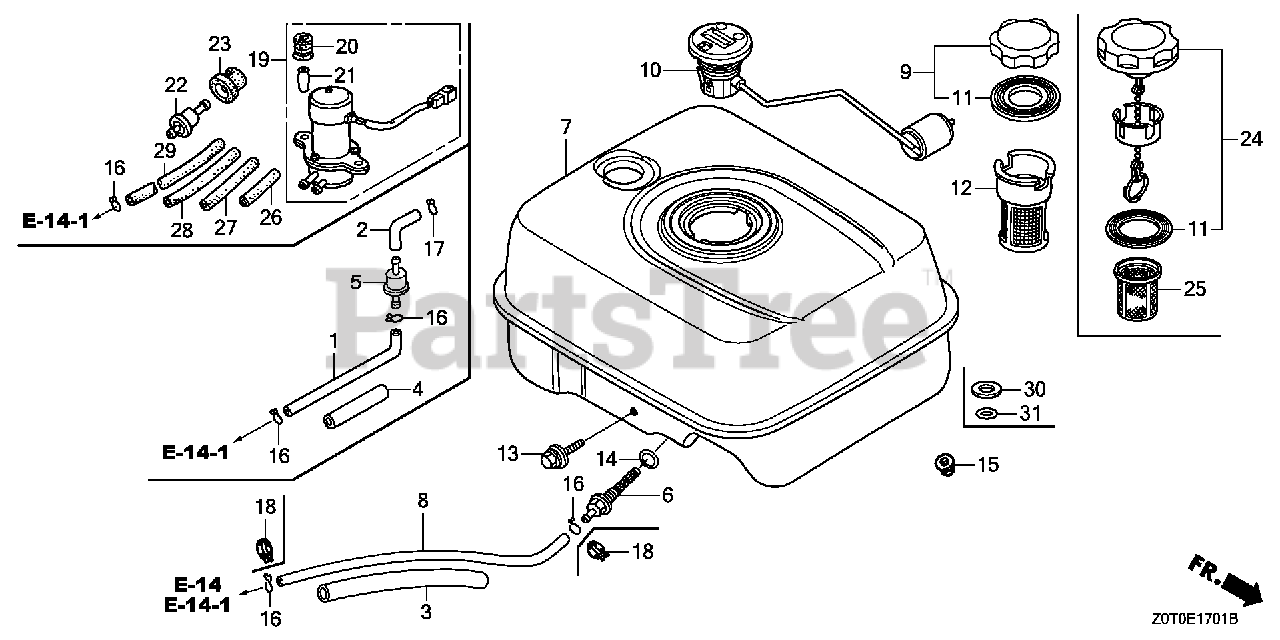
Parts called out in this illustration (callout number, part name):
3	RUBBER, SUPPORTER (107MM)
6	JOINT, FUEL TANK
7	TANK, FUEL *NH31* (MCKINLEY WHITE)
7	TANK, FUEL *NH1* (BLACK)
8	TUBE, FUEL (4.5X145) (FKM)
11	GASKET, FUEL FILLER CAP
11	GASKET, FUEL FILLER CAP (39X62X3) (TOUYOUSYA)
13	BOLT, FLANGE (6X29)
14	O-RING (14MM) (ARAI) Use up to Engine SN 2949254.
15	NUT, FLANGE (6MM)
18	CLIP, TUBE (D8)
24	CAP, FUEL FILLER
